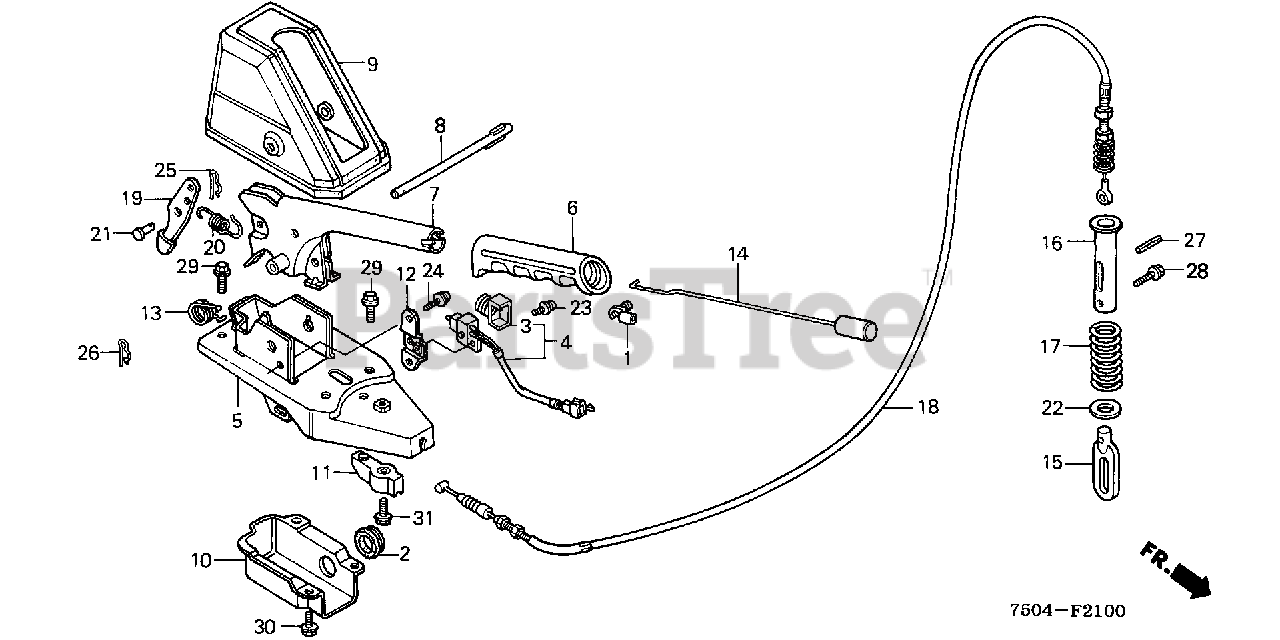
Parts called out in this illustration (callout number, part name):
1	JOINT, ROD
2	GROMMET, WIRE
3	COVER, SWITCH
4	SWITCH ASSY., PARKING BRAKE (NOT AVAILABLE)
5	BASE, PARKING BRAKE
6	GRIP, BRAKE LEVER
7	LEVER, PARKING BRAKE
8	PIN, BRAKE LEVER
9	PROTECTOR, PARKING BRAKE
10	COVER, BRAKE (LOWER)
11	GUIDE, CABLE
12	BRACKET, SWITCH
13	SPRING, BRAKE LEVER RETURN
14	PUSHER, RATCHET
15	JOINT, PARKING BRAKE
16	PIPE, PARKING BRAKE SPRING SETTING
17	SPRING, PARKING BRAKE LOAD SETTING
18	CABLE, PARKING BRAKE (NOT AVAILABLE)
19	LEVER, LOCK (NOT AVAILABLE)
20	SPRING, RATCHET RETURN
21	PIN, SEAT HINGE
22	WASHER, PLAIN (17.2MM)
22	WASHER, BRAKE SPRING SETTING
23	SCREW-WASHER (4X14)
24	SCREW-WASHER (5X12)
25	PIN, LOCK (6MM)
26	PIN, LOCK (8MM)
27	PIN, SPRING (6X25)
28	BOLT, FLANGE (6X12)
29	BOLT, FLANGE (6X10)
30	BOLT, FLANGE (6X10)
31	BOLT, FLANGE (6X12)
